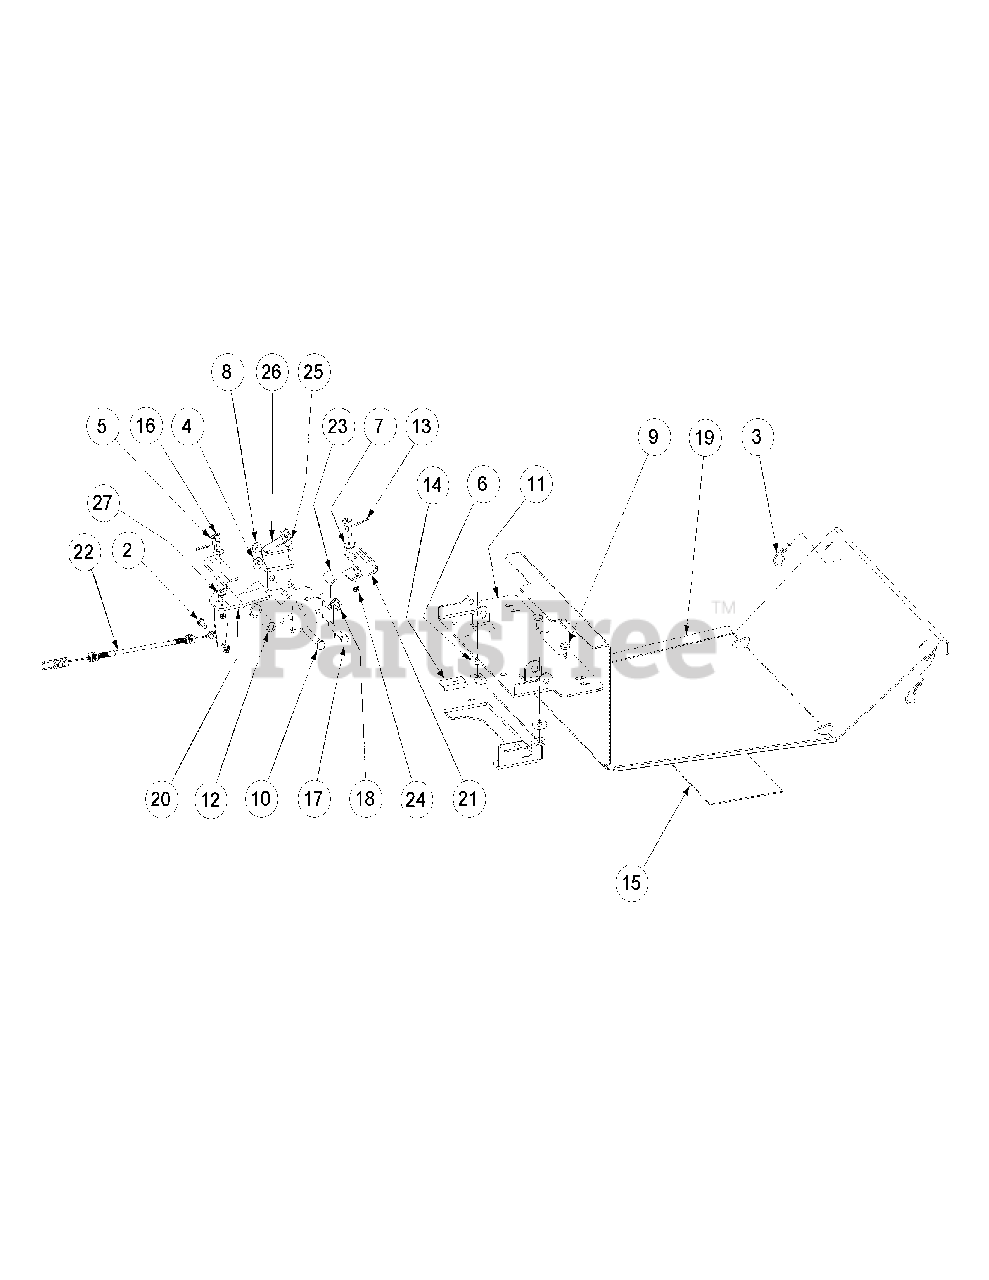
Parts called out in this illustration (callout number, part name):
1	Lock Nut w/Nylon Insert
2	Hex Cap Screw, 1/4-20, .75
3	Hair Pin, 3/8" - 1/2"
4	Nut, Hex, Flange Lock, 3/8-16
5	Clevis Pin, 1/4 x 1/2, SS
6	Washer
7	Bell Washer, .265 x .75 x .062
8	Nut Lock, Hex Flange 5/16-18
9	Rubber Bumper, .62 OD x .22 Thick
10	Hex Cap Screw, 3/8-16 x 2.75
12	Spacer, .39ID x .63OD x 1.75LG
13	Cotter Pin, .072 x 1.12 Lg
14	Support, Seat Bracket
15	Label, Belt Routing and Lubrication
16	Shoulder Bolt, 1/4x1/4
17	Hex Cap Screw, 5/16-18 x 2.5
18	Deck Lift Spring, Left Hand
19	Floor Plate Assembly
20	Foot Pedal Latch Lever Assembly
21	Rate Plate Pad
22	Rate Plate On/Off Cable
23	Foot Pedal Latch Assembly
24	Nut, w/ Star Washer, 10-24
25	Light Indicator
26	Light Indicator Bracket
27	Washer, 1/4, SS
